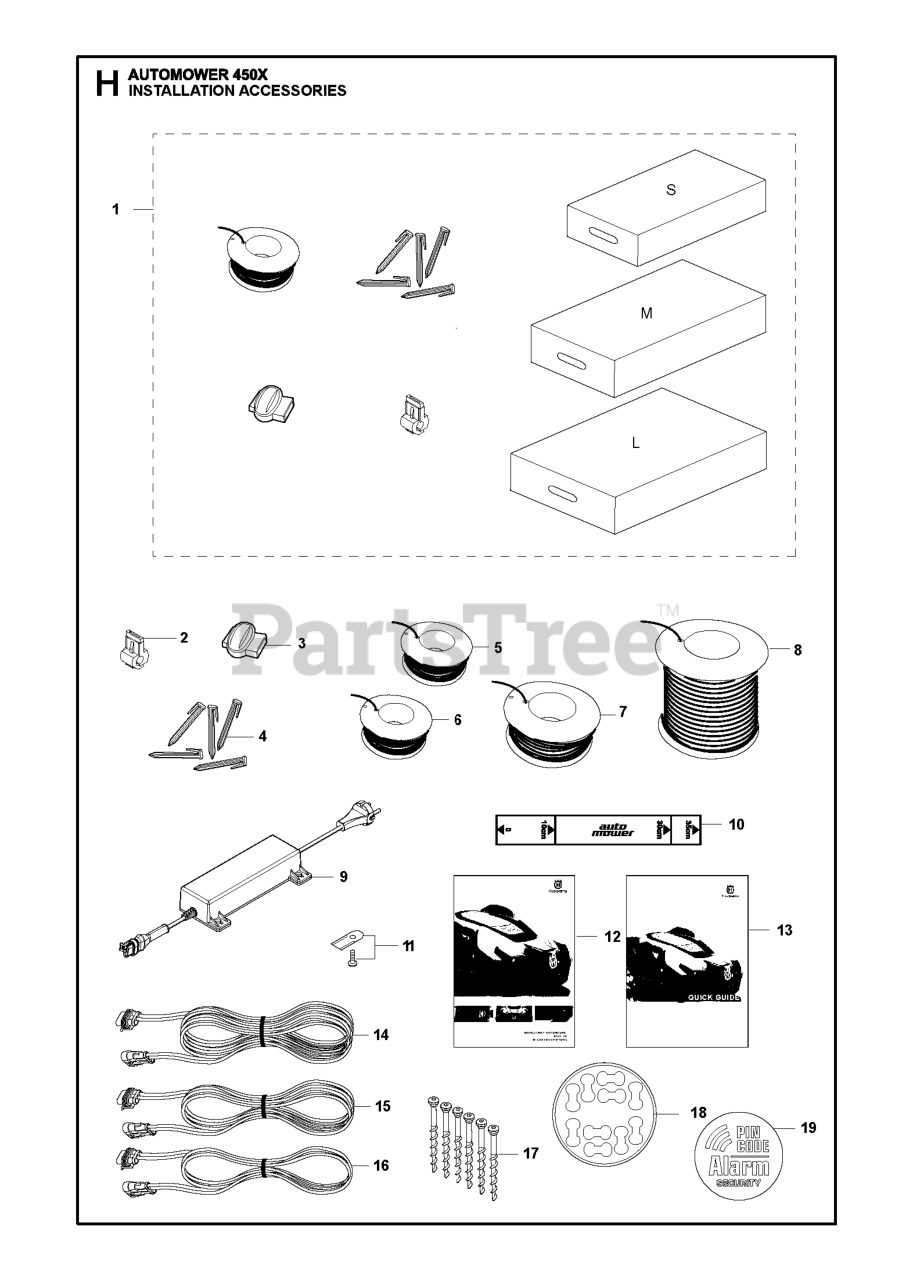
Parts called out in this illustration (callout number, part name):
1	SMALL AUTOMOWER INSTALL KIT
1	LARGE AUTOMOWER INSTALL KIT
1	MED AUTOMOWER INSTALL KIT
2	CONNECTOR 5 PCS, BLISTER
2	BRAKER
3	COUPLER SPLICER, 5 PCS,
3	COUPLER SPLICER, 100 PCS
3	SPLICE KIT
4	STAPLE 100 PCS
4	STAPLE 100 PCS, BLISTER
5	WIRE 150M, BLISTER
5	WIRE BOUNDARY 150M
6	WIRE 250M
7	WIRE 500M
8	WIRE (800M)
9	POWER UNIT POWER SUPPLY UNIT 7
10	RULER / CENTIMETERS
11	BLADE KIT HUSQVARNA 9 PCS 50HR
11	BLADE SET 45 PCS
11	BLADE SET 300 PCS. CARBON STEE
14	CABLE LOW VOLTAGE CABLE AM450
15	CABLE LOW VOLTAGE CABLE AM450
16	CABLE LOW VOLTAGE CABLE AM450
17	SCREW 3 PCS, BLISTER PACK
17	SCREW KIT CS
18	STICKER CABLE MARKERS KIT 10PC
19	LABEL SECURITY
